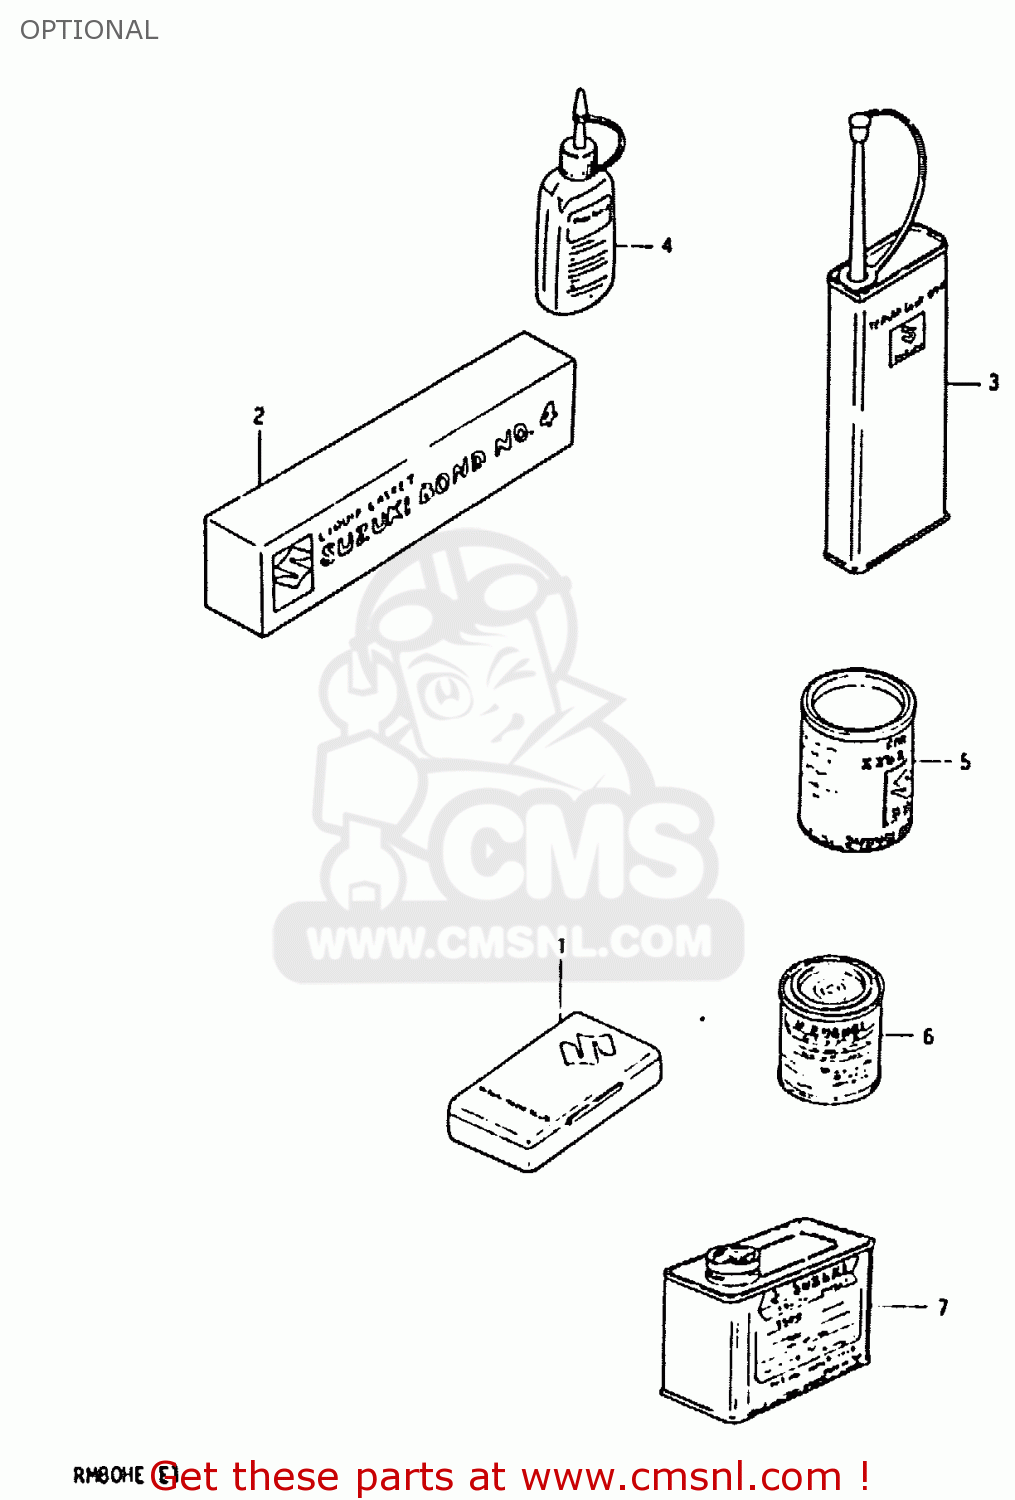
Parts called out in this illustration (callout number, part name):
1	TUBE REPARING TOOL
2	BOND 1104
3	THREAD LOCK NO.1401 CLEAR 200G
4	THREAD LOCK NO
5	GREASE(C)EP2 LITHIUM 150G
6	PAINT,BLACK
7	PAINT (BLACK)
